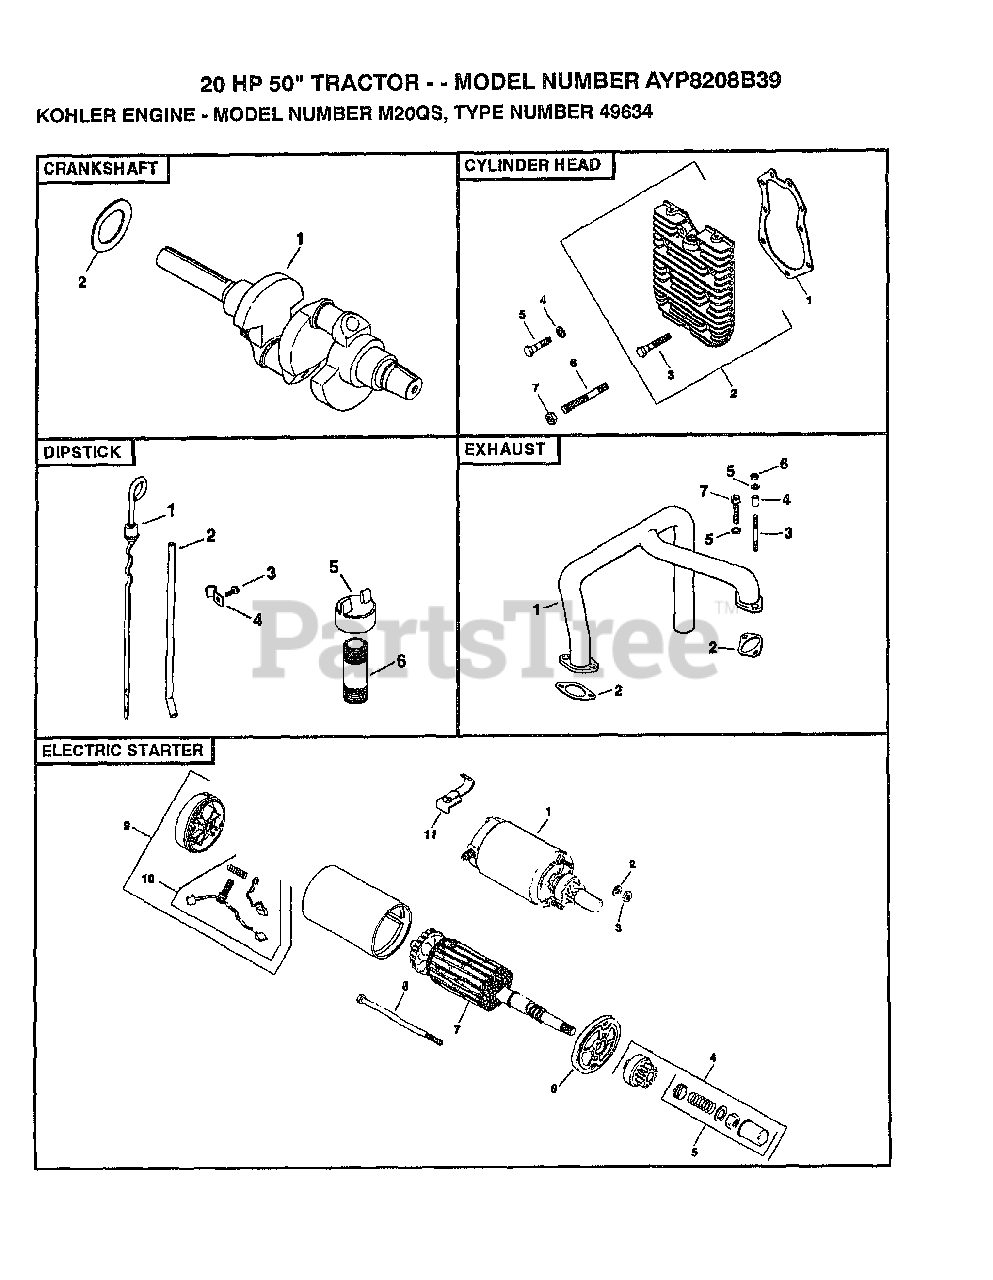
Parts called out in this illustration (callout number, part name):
1	DIPSTICK, BLADE 11-5/16
1	STARTER ASSEMBLY
2	WASHER, .119/.122 (A.R.)
2	WASHER, .128/.131
2	WASHER, .137/.140 (A.R.)
2	KIT, CYL. HEAD
2	TUBE, OIL LEVEL
2	GASKET, EXHAUST
2	WASHER
3	SCREW
3	NUT
4	WASHER
5	WASHER
5	KIT, DRIVE PARTS
6	NUT
6	CAP, DRIVE END
7	NUT
7	SCREW
9	CAP, DRIVE END
11	BRACKET, MOUNTING
